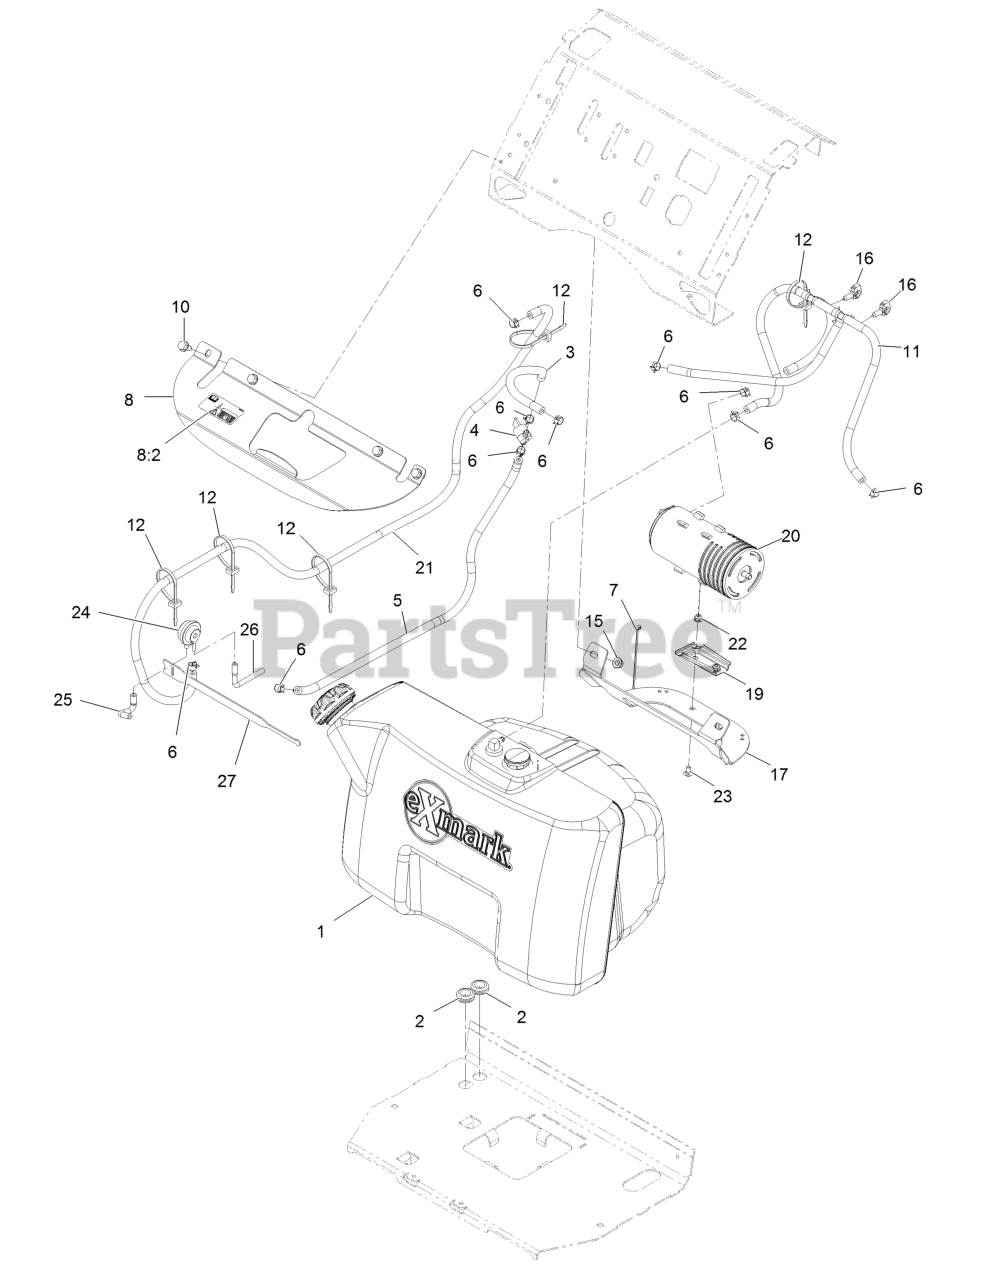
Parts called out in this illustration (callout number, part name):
1	Tank ASM-
2	Grommet
3	Hose-Fuel
4	Valve-Fuel
5	Hose-Fuel
6	Clamp-Hose
7	Tie-Cable 5 1/2 (Small)
8	Bracket-Tank
8:2	Decal-Fill, Fuel
10	Screw-HWH 5/16-18 X 3/4 Tf
11	Vent ASM
12	Tie-Cable
15	Nut-Nyloc 5/16-18 Flg
16	Clip-Harness
17	Bracket,Carb Canister
19	Bracket-Canister, Carbon
20	Canister-Carbon, 800Cc
21	Hose-Fuel .25 X 60.00, J30R7
22	Nut-Nyloc 1/4-20 Flg
23	Screw-CARR
24	Valve-Control, Vacuum
25	Hose-Vent, Formed
26	Hose-Vent, Formed
27	Strap-Velcro, Cable Tie
